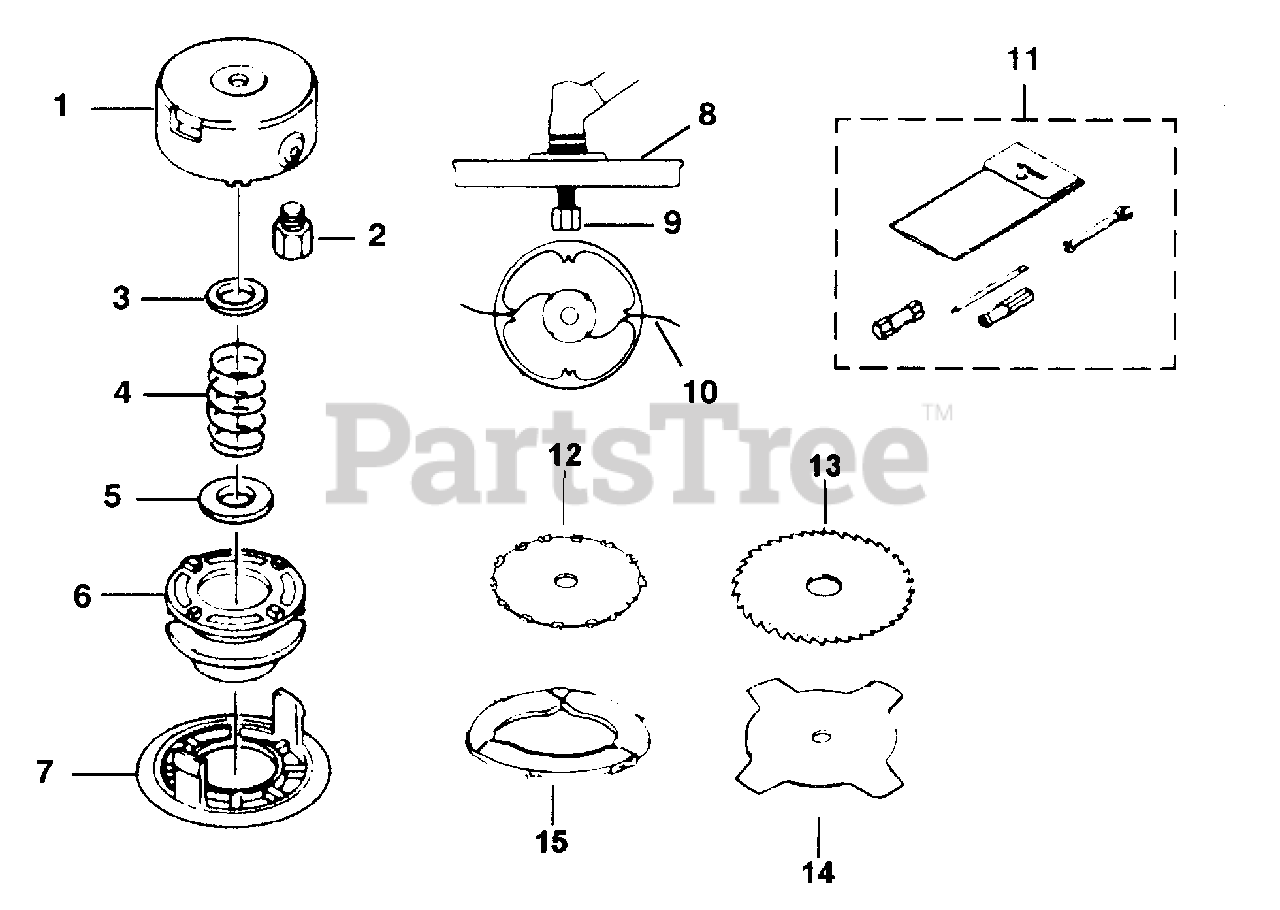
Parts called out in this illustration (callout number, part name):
1	HEAD BODY
2	ARBOR BOLT
3	SPRING PLATE
4	SPRING
5	SPRING PLATE
6	SPOOL
8	FIXED LINE HEAD ASSY
9	ARBOR BOLT
10	GREEN LINE .105 X 20ft.
12	8" XRT BLADE
13	8" SAW BLADE
14	8" QUAD BLADE
15	BLADE COVER
